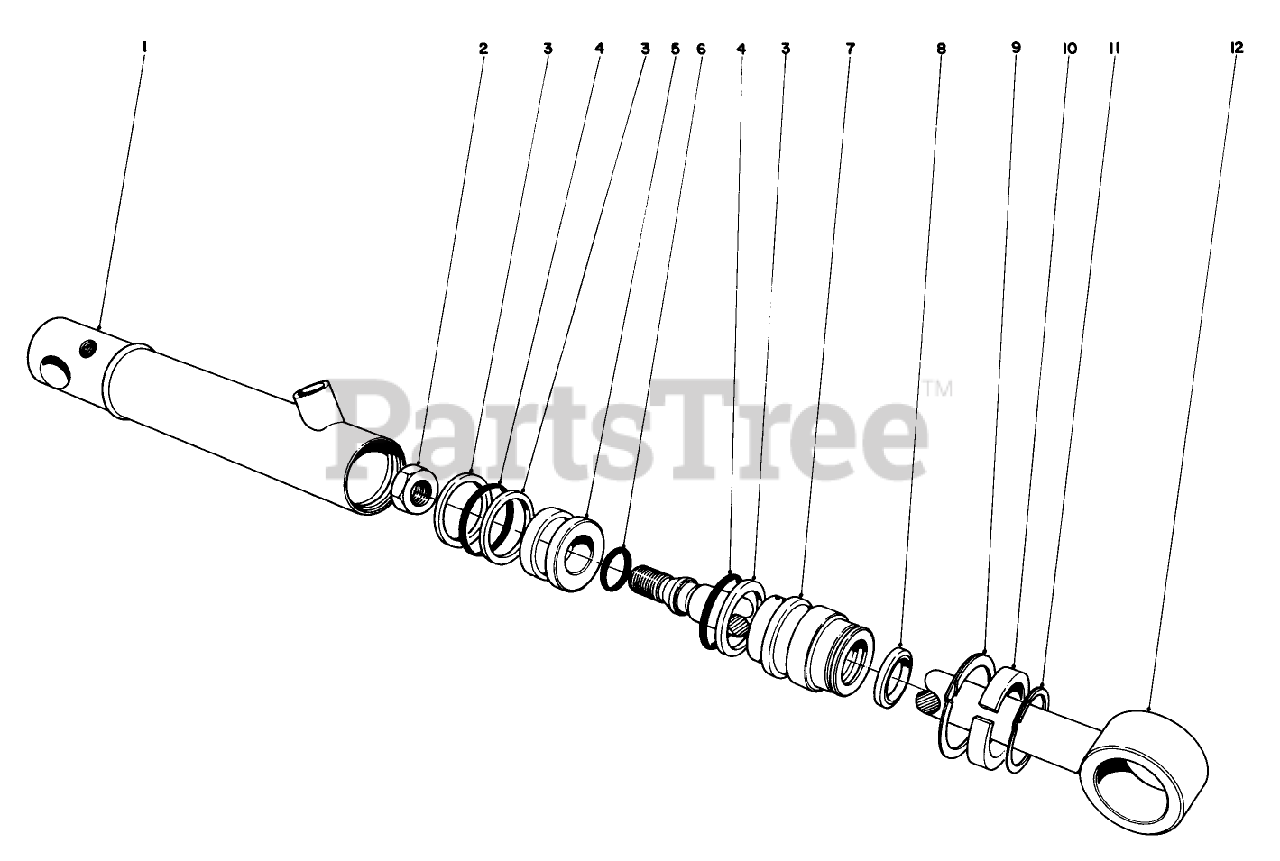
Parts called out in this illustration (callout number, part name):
1	Barrel with Clevis & Ports
2	Nut
3	Back Up Washer
5	PISTON
9	Leather
10	Seal Dust
11	RING-RETAINING
12	SHAFT W/CLEVIS
